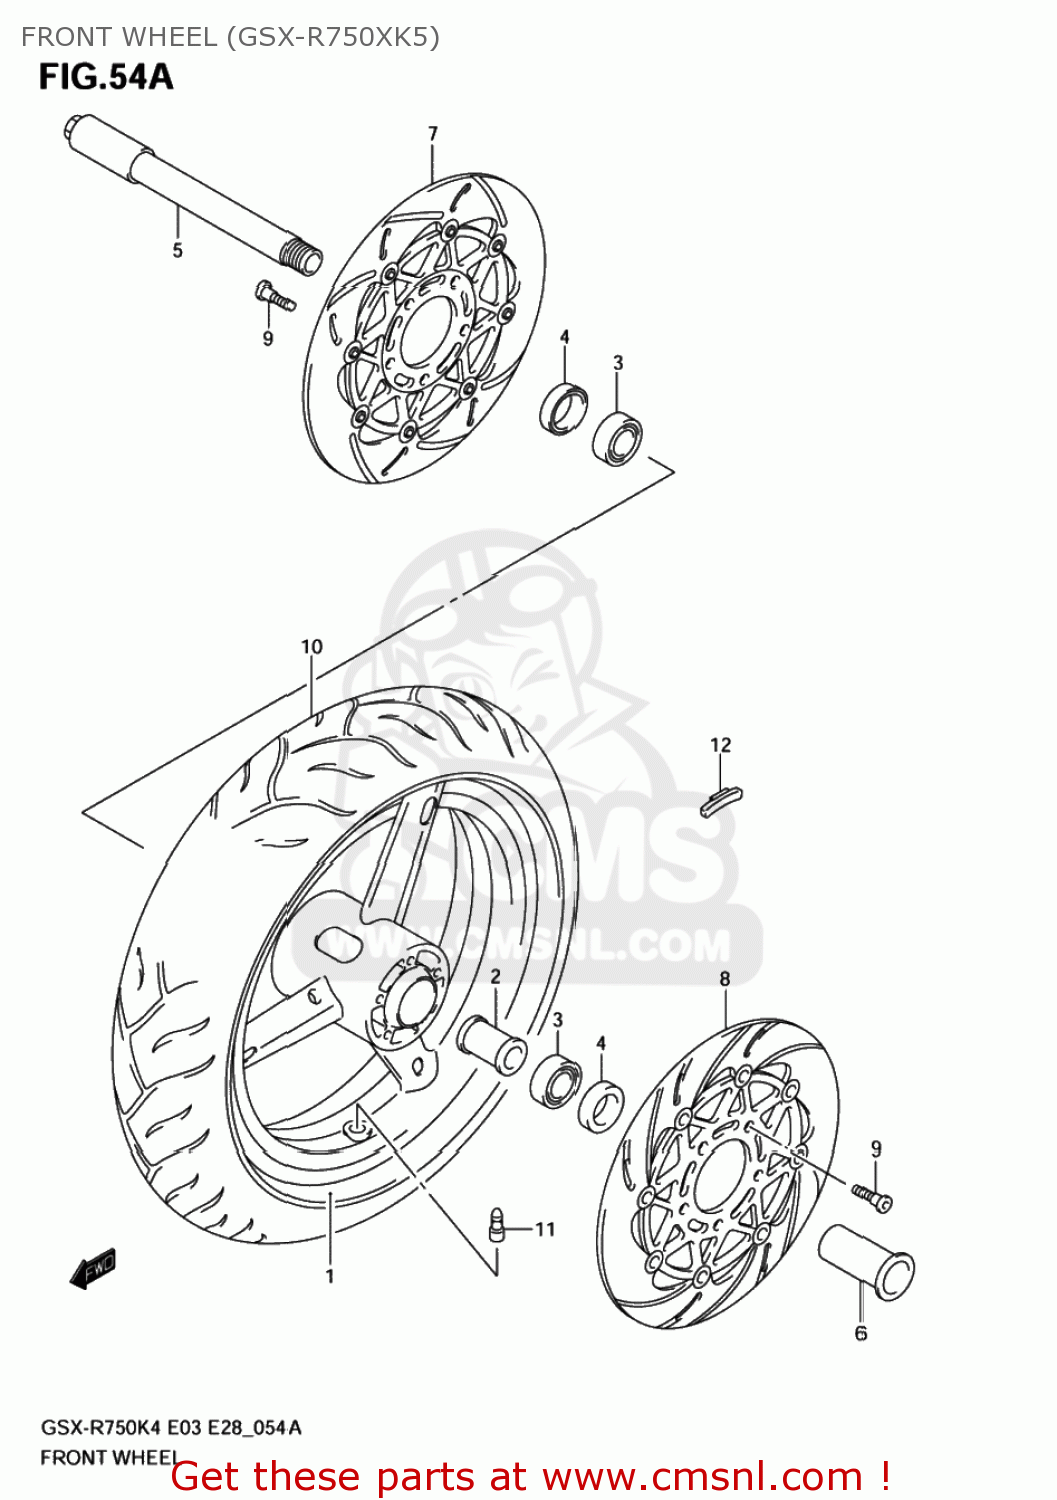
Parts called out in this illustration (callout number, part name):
1	WHEEL,FR(17M/CXMT3.50)
2	SPACER,FR HUB BEARING
3	BEARING(25X52X15)
4	SEAL,OIL(32X52X7)
5	AXLE,FR
6	NUT,FR AXLE
7	DISC,FR BRAKE,R
8	DISC,FR BRAKE,L
9	BOLT(8X33)
10	TIRE, FRONT 120/70 ZR17 M/C
11	VALVE ASSY,WHEEL RIM(TR412)
12	WEIGHT,WHEEL BALANCE 10G
